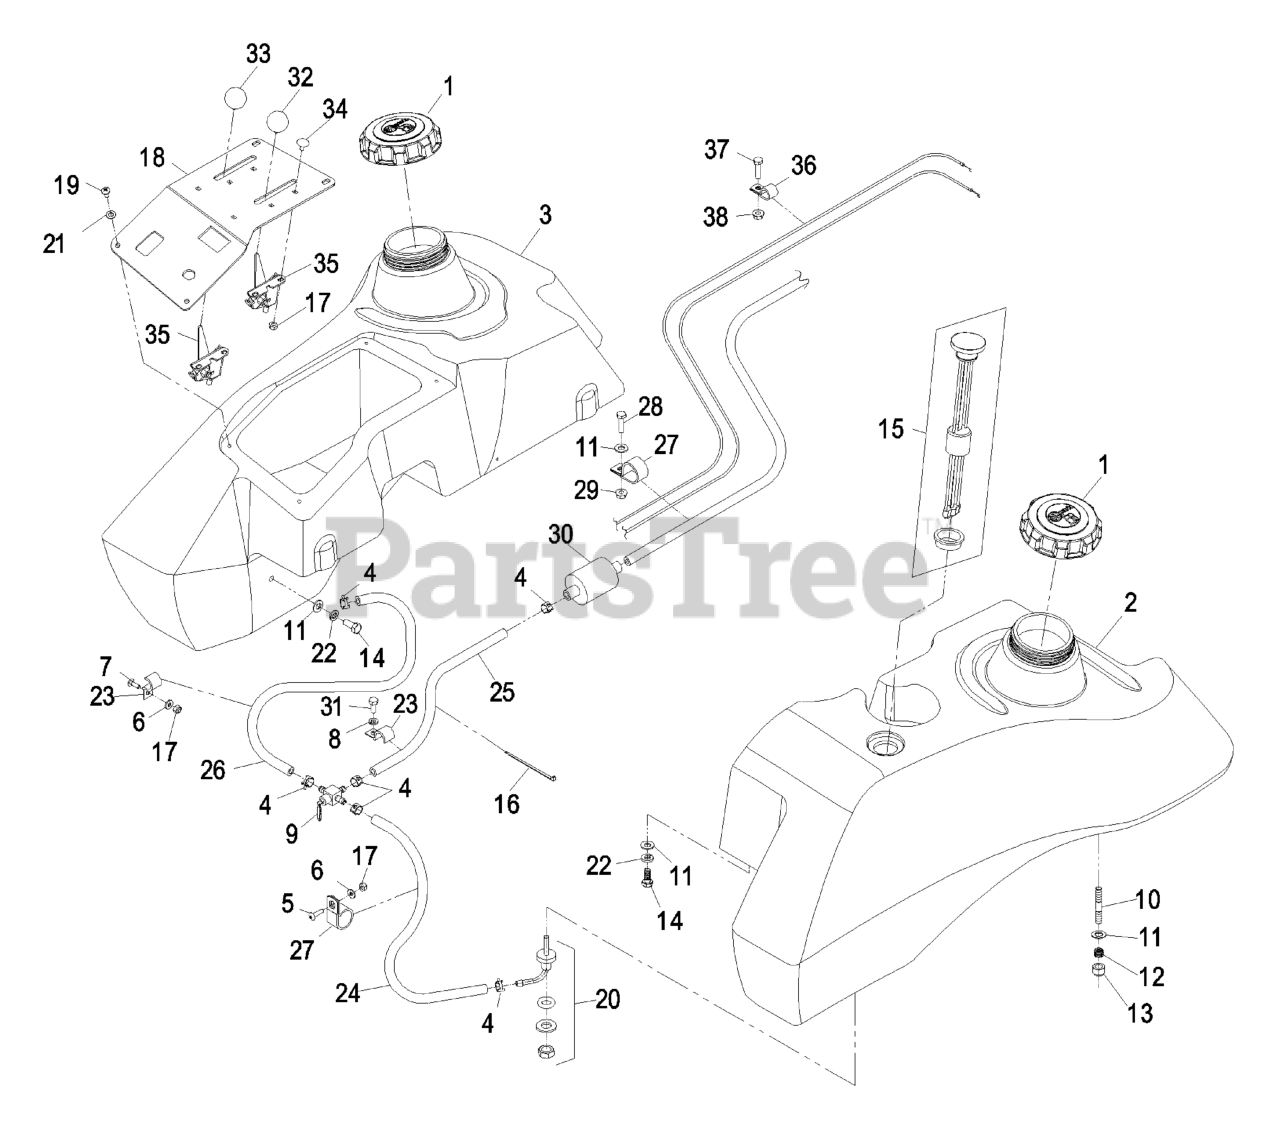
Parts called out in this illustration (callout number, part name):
2	KIT,FUEL TANK LH LZXS
3	KIT,FUEL TANK RH LZXS
5	SCREW-HEAD, TRUSS
6	WASHER-FLAT
7	BOLT-CARR
8	WASHER-LOCK
9	VALVE-FUEL
10	STUD
11	WASHER-PLAIN
12	SPRING-TANK, FUEL
13	NUT-LOCK, NI
14	SCREW-HH
15	KIT, CT FUEL GAGE REPL.
16	TIE-PLASTIC
17	NUT-LOCK, NI
18	KIT,CTRL PANEL W/DECALS L
19	SCREW-PTH
20	FITTING-FUEL, BULKHEAD
21	WASHER-SPRING
22	WASHER-LOCK
23	CLIP-HALF, LOOM
24	HOSE-FUEL
25	HOSE-LINE, FUEL
27	CLIP-LOOM
28	SCREW-HH
30	Briggs & Stratton P/N 695327 Fuel Filter
31	SCREW-HH
32	KNOB-BALL
33	KNOB-BALL, BLACK
34	BOLT-CARR
35	CABLE-THROTTLE
36	CLIP-LOOM
37	SCREW-HH
